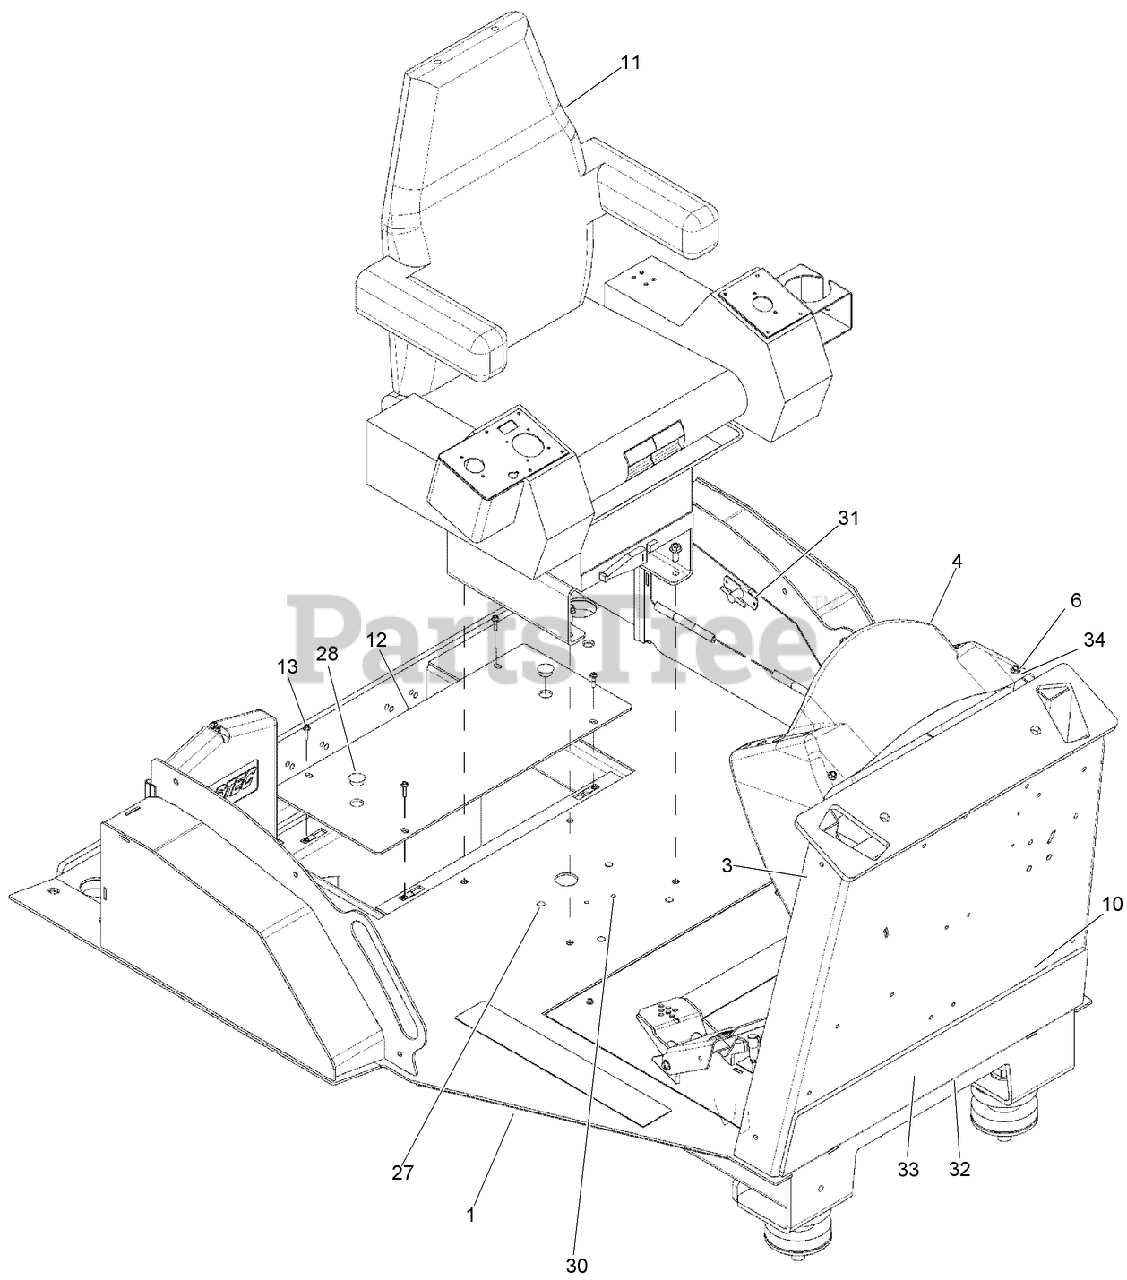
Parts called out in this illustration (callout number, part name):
1	WELDMENT - Operators Station
4	PANEL-Dash
6	SCREW, METRIC FLANGE FULL - M8 x 25
10	SCREW-HHF
11	SEAT ASM
12	PLATE - Battery Cover
13	SCREW, METRIC FLANGE w/BODY-M6 x 25
27	PLUG - Dome 0.500 in Hole Black Nylon
28	PLUG-DOME
30	PLUG-DOME
32	PLATE - Wire Harness Cover
33	NUT, METRIC FLANGE PREVAILING - M6 Zinc
34	NUT-TORQUE, PREVAILING
